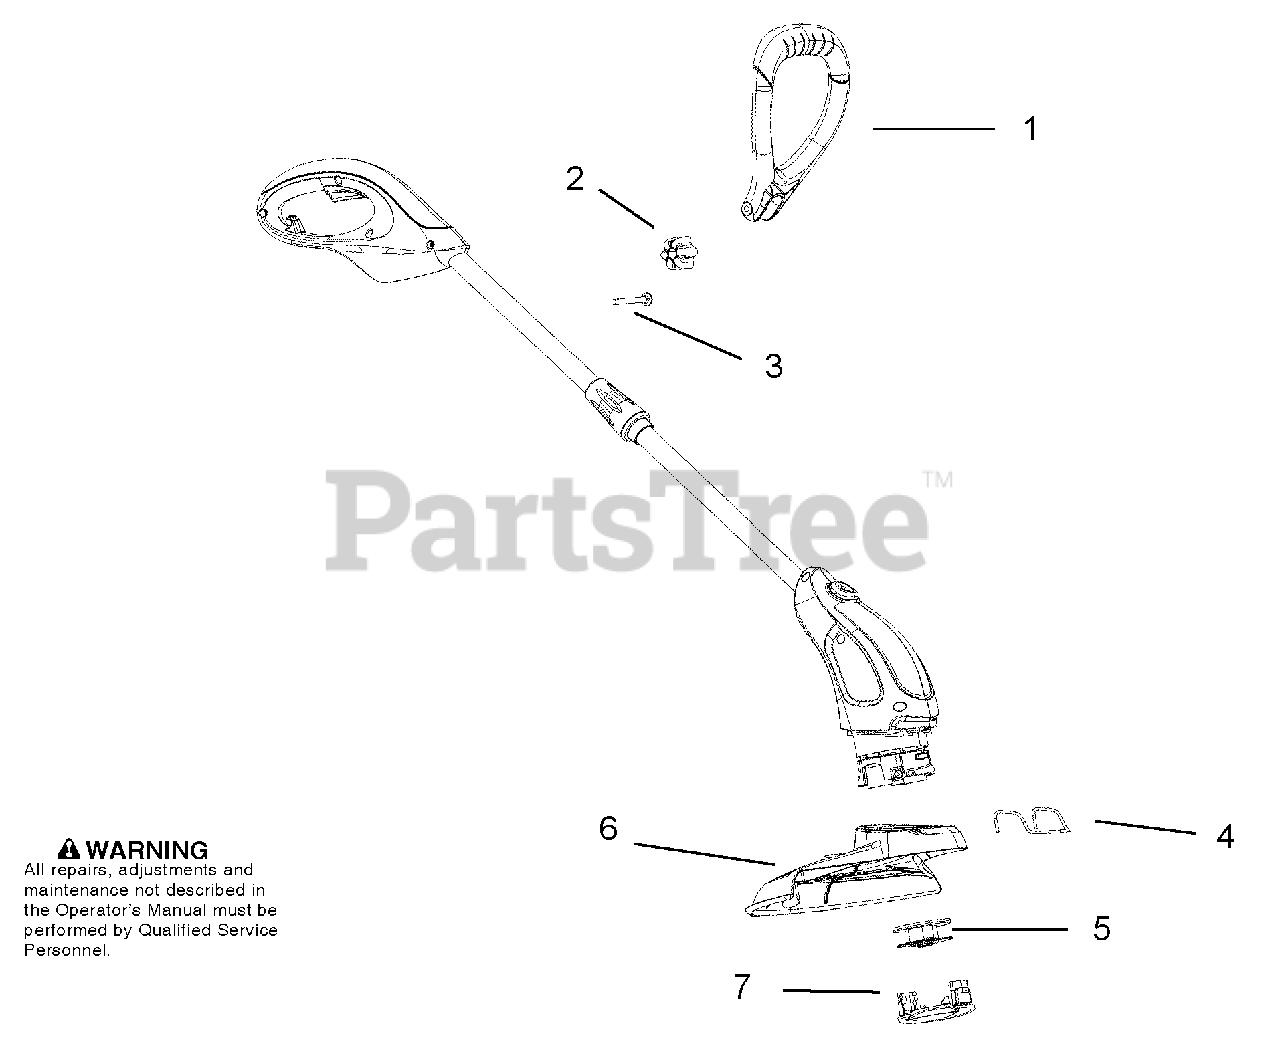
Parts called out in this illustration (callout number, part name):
1	Assit Handle
3	Bolt Carriage, M6 X 1
4	Edge Guide
5	Spool with 0.065" Trimmer line
6	Shield Assembly
7	Spool Cap
